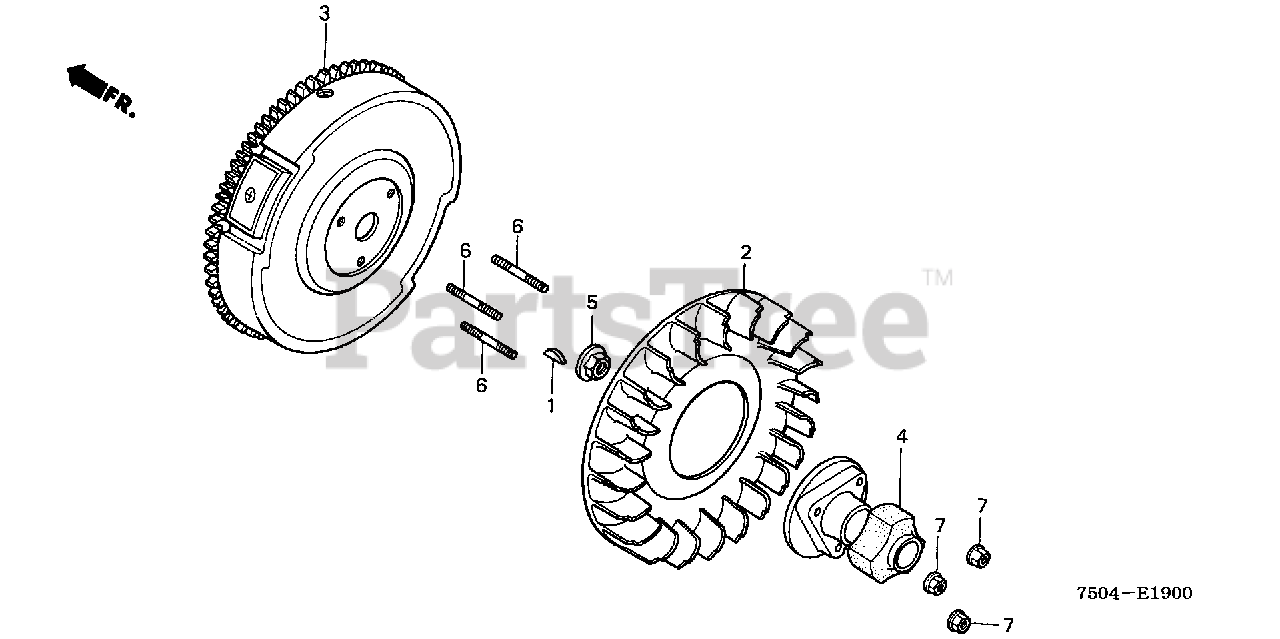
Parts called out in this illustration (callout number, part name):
1	KEY, SPECIAL WOODRUFF (25X18)
2	FAN, COOLING
4	DAMPER A, PROPELLER SHAFT
5	NUT, SPECIAL (16MM)
6	BOLT, STUD (8X32)
7	NUT, FLANGE (8MM)
